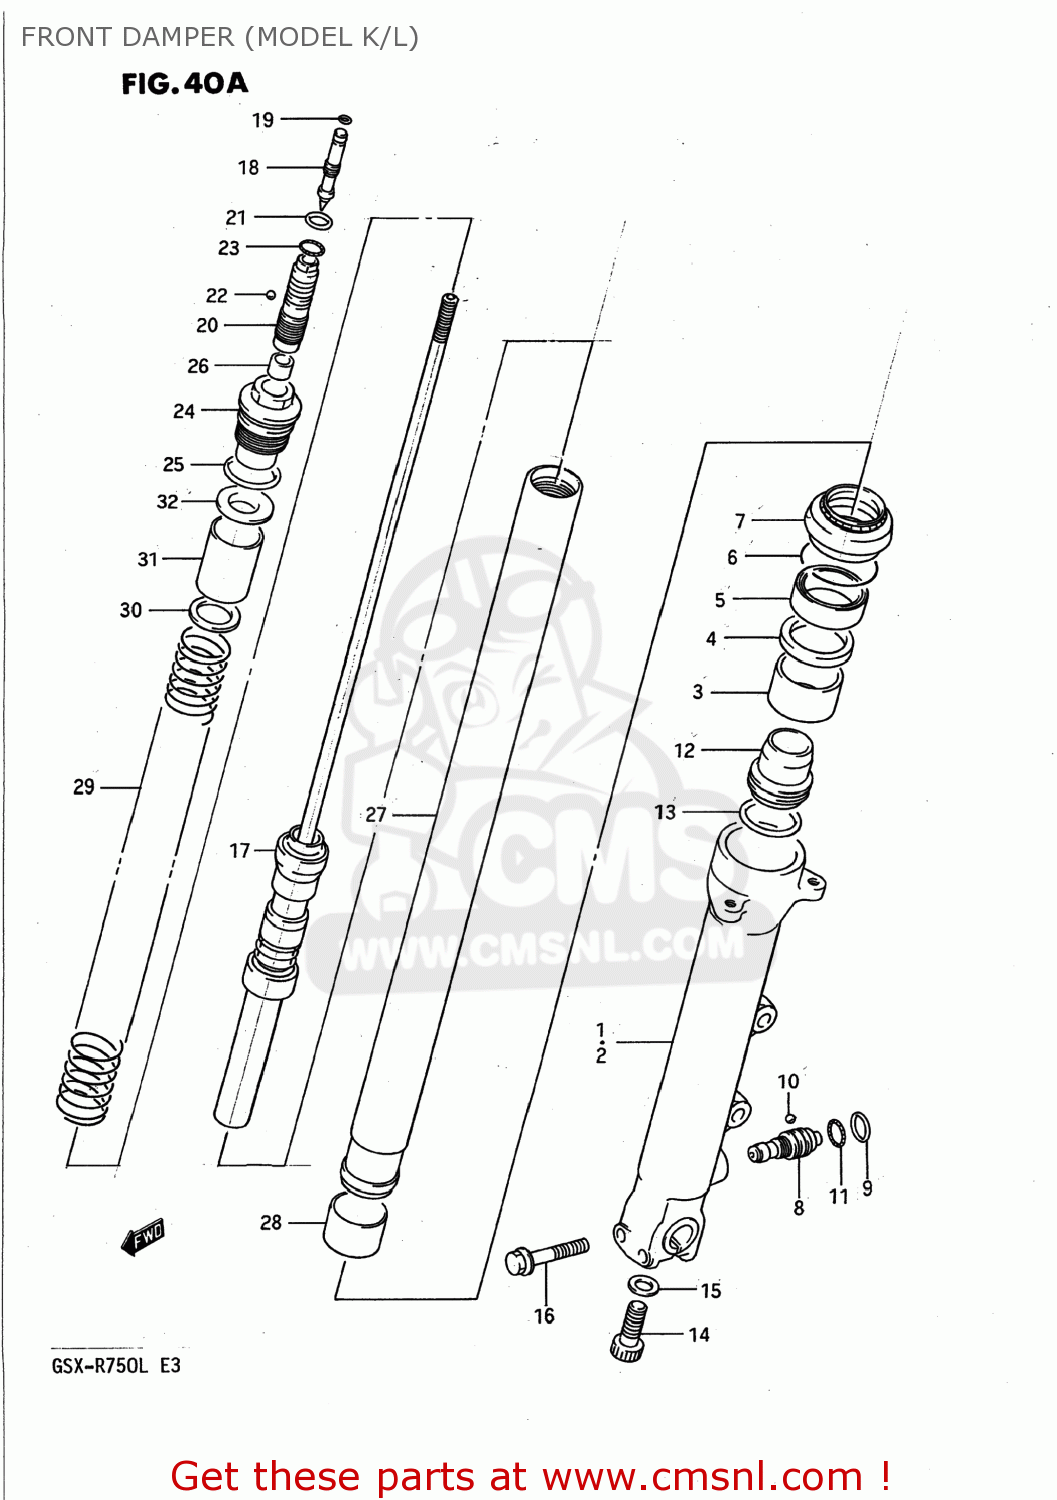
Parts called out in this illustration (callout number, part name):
1	TUBE,OUTER,RIGHT
2	TUBE,OUTER,LEFT
3	BUSHING,GUIDE
4	SPACER,SEAL
5	OIL SEAL,FRONT FORK
6	CIRCLIP,FORK OIL SEAL
7	SEAL DUST
8	PIECE,ADJUSTER
9	O RING
10	BALL
11	EXPANDER
12	PIECE,OIL LOCK
13	O RING
14	BOLT
15	WASHER(10X15X1.5)
16	BOLT
17	DAMPER
18	PIECE,ADJUSTER UPR
19	O RING
20	ADJUSTER,SPRING
21	O RING
22	BALL
23	EXPANDER
24	BOLT,FORK
25	O RING
26	NUT
27	TUBE,FORK,INNER
28	BUSH,SLIDE
29	SPRING
30	SEAT,SPRING LWR
31	COLLAR,SPRING(35X37X50)
32	SEAT,SPRING UPR
